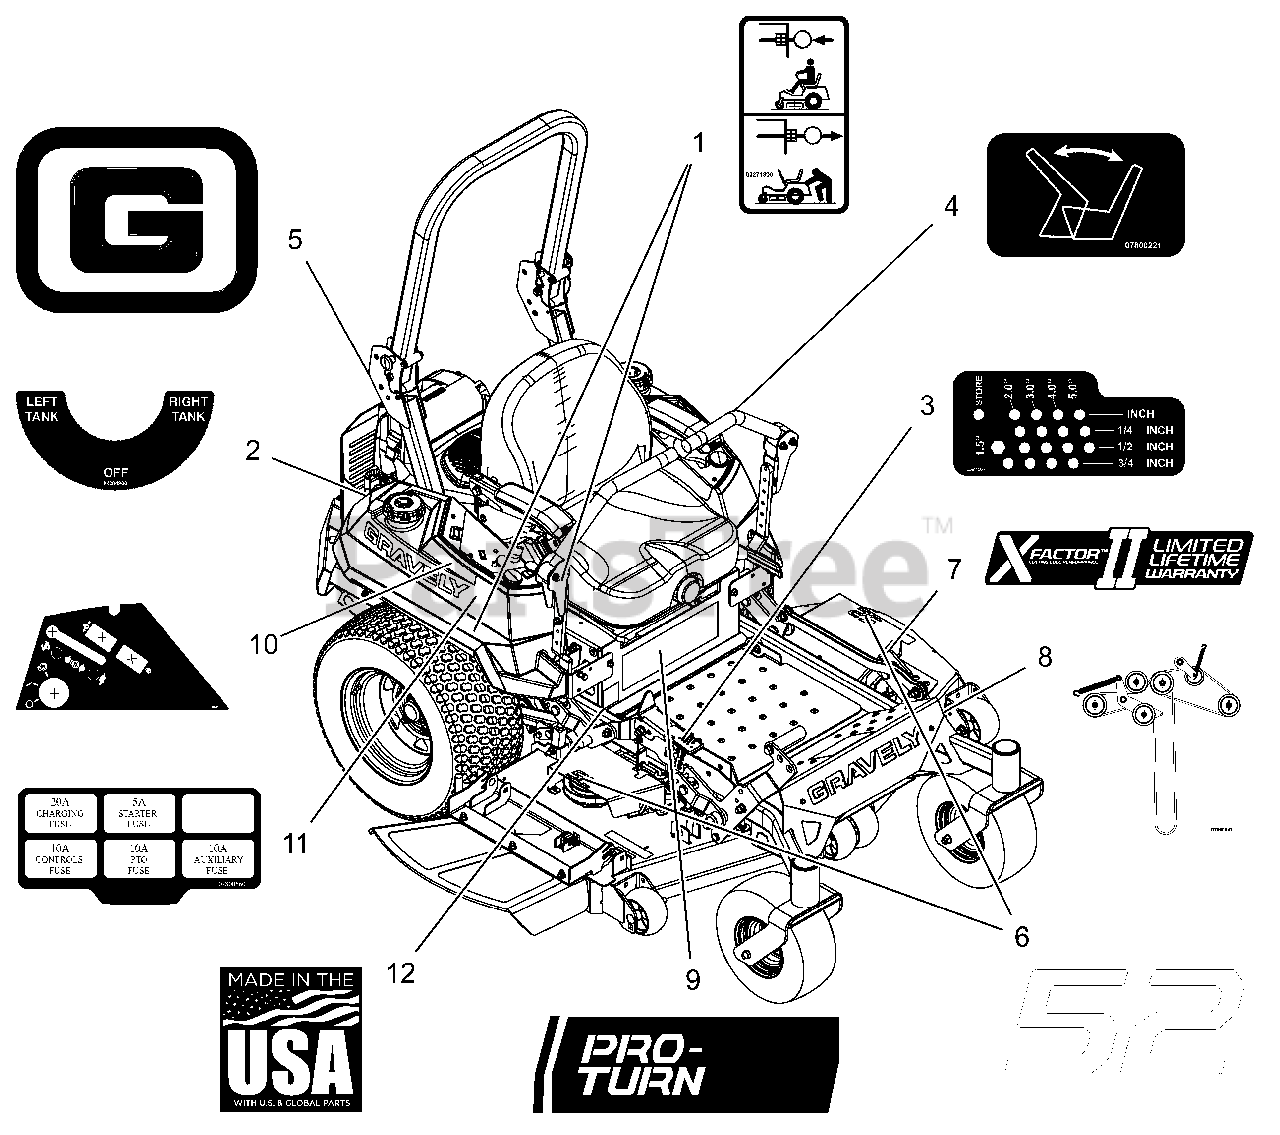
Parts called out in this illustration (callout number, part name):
1	DECAL, TRANSMISSION DISCONNECT
2	DECAL, FUEL VALVE
3	DECAL, HEIGHT OF CUT
4	DECAL - SEAT RELEASE
5	DECAL, GRAVELY BRAND
6	DECAL, 52"
7	DECAL, X-FACTOR DECK
8	DCL,BELT ROUTE-RH V-SIDE IDLER
9	DECAL, PRO-TURN 152
10	DECAL, EFI CONTROL PANEL
11	DECAL, FUSE BLOCK
12	DECAL, MADE IN USA
